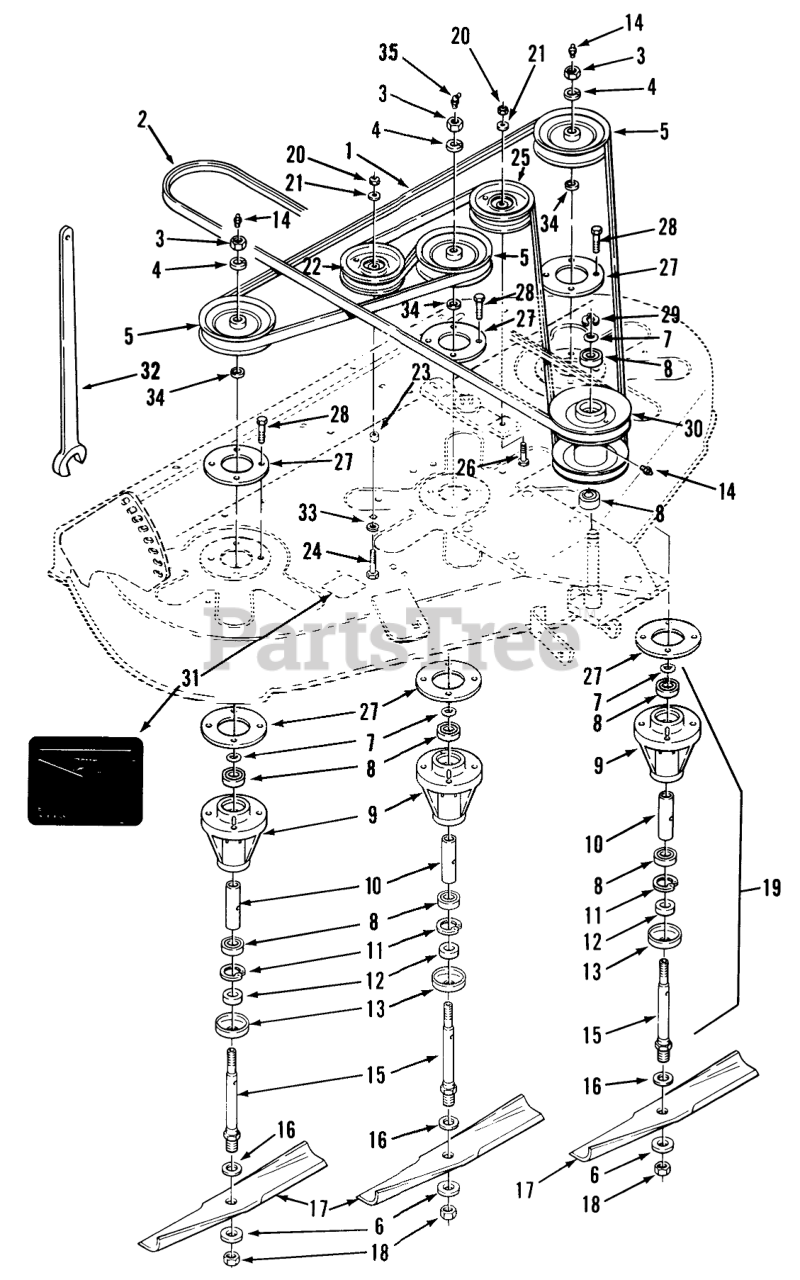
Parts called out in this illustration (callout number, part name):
1	V-BELT
2	V-BELT
3	NUT-JAM
4	WASHER-LOCK
5	PULLEY-SPINDLE
6	WASHER-FLAT
7	O RING
8	BEARING-BALL
9	HOUSING-SPINDLE
11	Ring-Snap
12	SPACER-BLADE
13	CUP-SPINDLE
14	FITTING-GREASE
15	SHAFT-SPINDLE
16	Washer
17	BLADE KIT
18	NUT-JAM
19	Spindle Assembly
20	NUT-LOCK, NI
21	WASHER-FLAT
22	Pulley-Idler
23	SPACER
24	SCREW-CARR
25	PULLEY-FLAT IDLER
26	SCREW-HH
27	SPACER-SPINDLE
28	SCREW-HH
29	RETAINING RING
30	PULLEY-COUNTER SHAFT
31	DECAL-BELT INSTALL
32	Spindle Wrench
34	Washer
35	FITTING-GREASE
